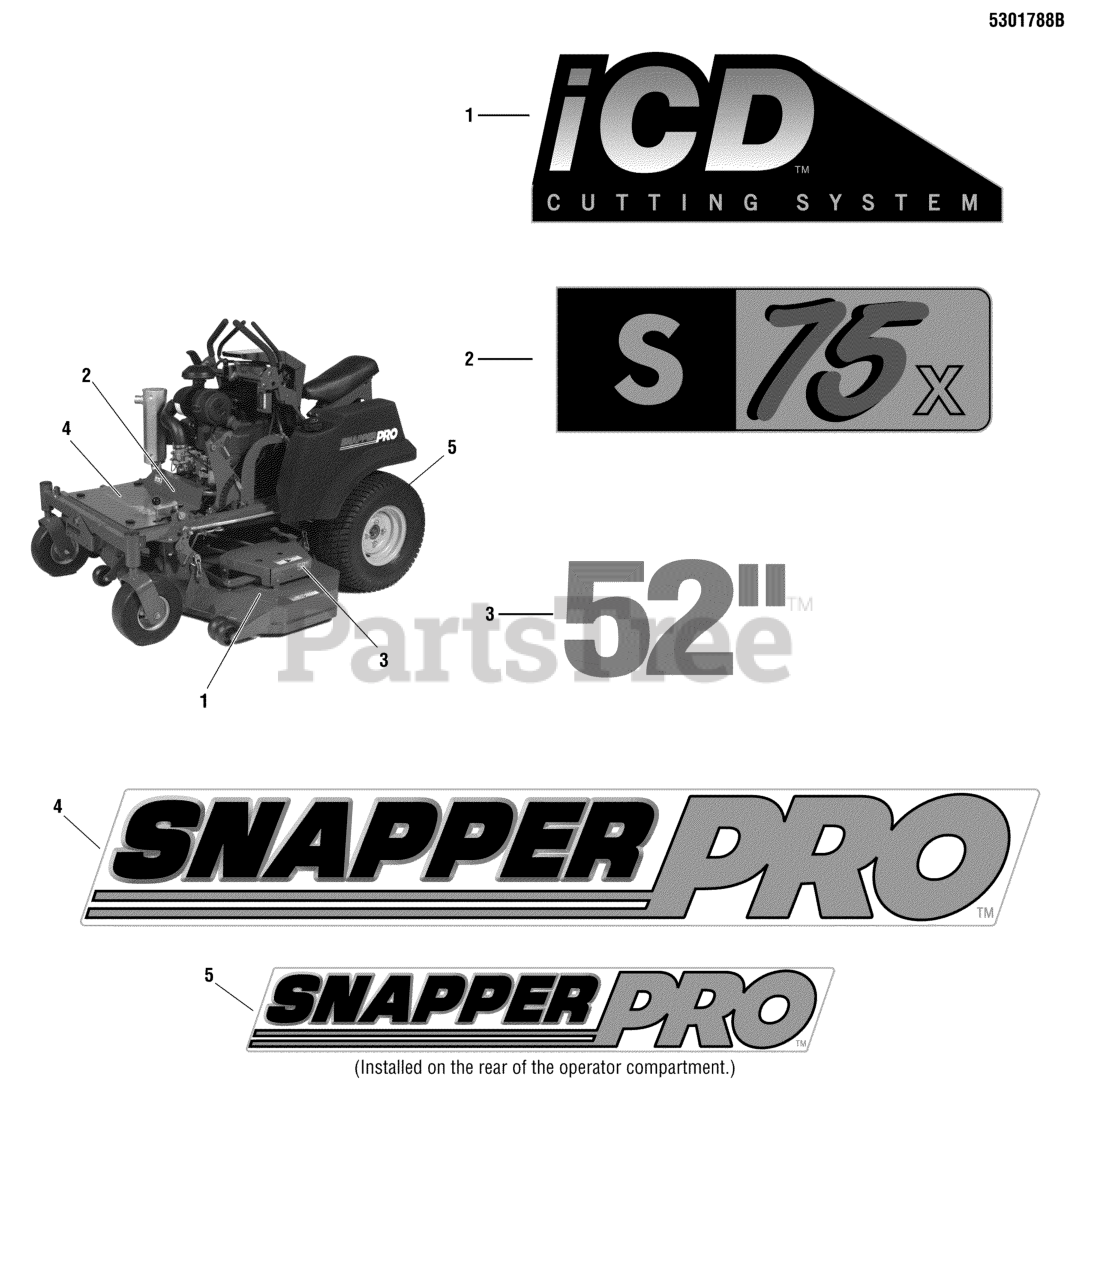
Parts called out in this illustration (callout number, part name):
1	DECAL, ICD CUTTING SYSTEM
2	DECAL, S75X
3	DECAL, 52
4	DECAL, SNAPPER PRO, FRONT
5	DECAL, SNAPPER PRO, REAR
